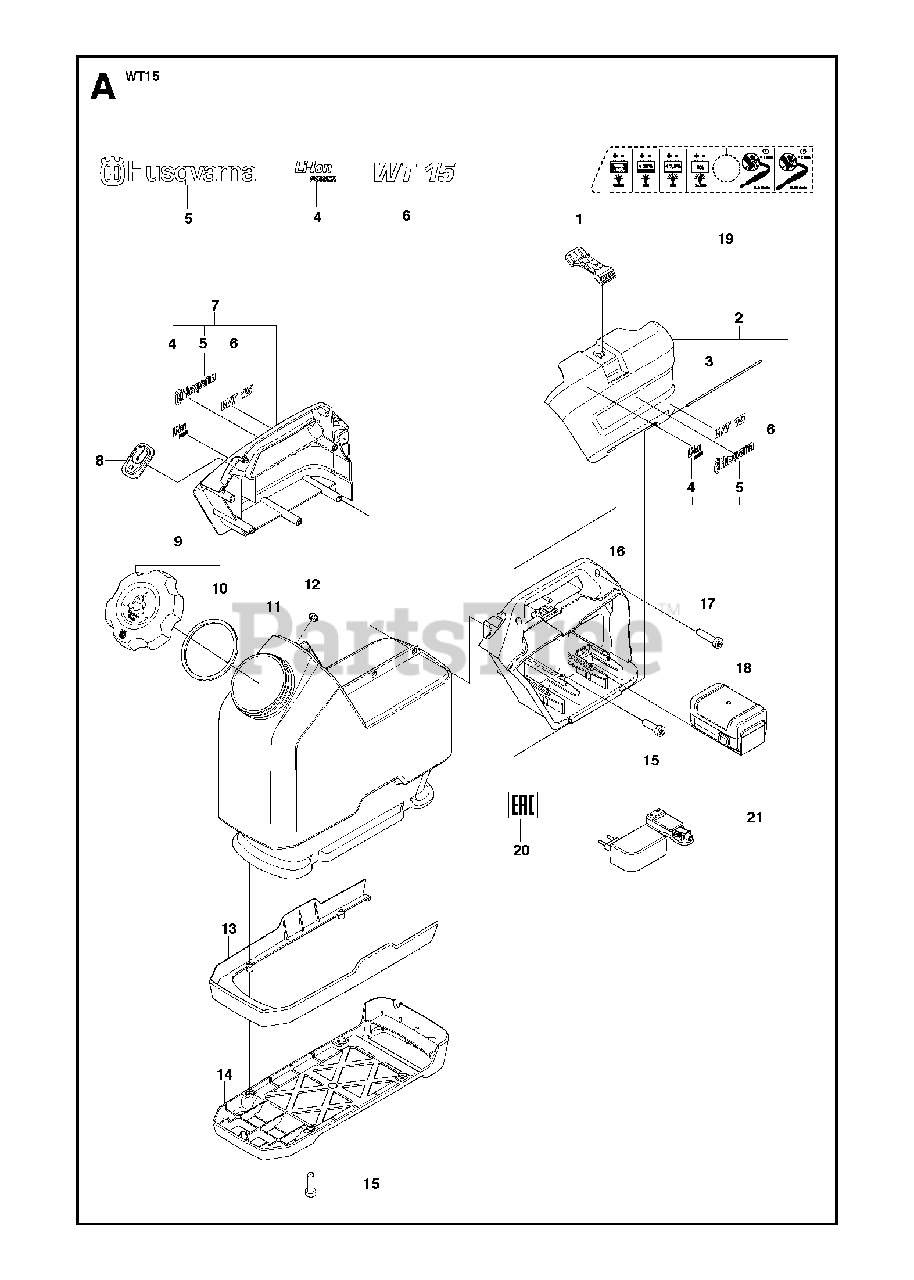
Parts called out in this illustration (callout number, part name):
9	HUB CAPIncl. 10
15	SCREW ITXSCT
17	SCREW ITXSCT
